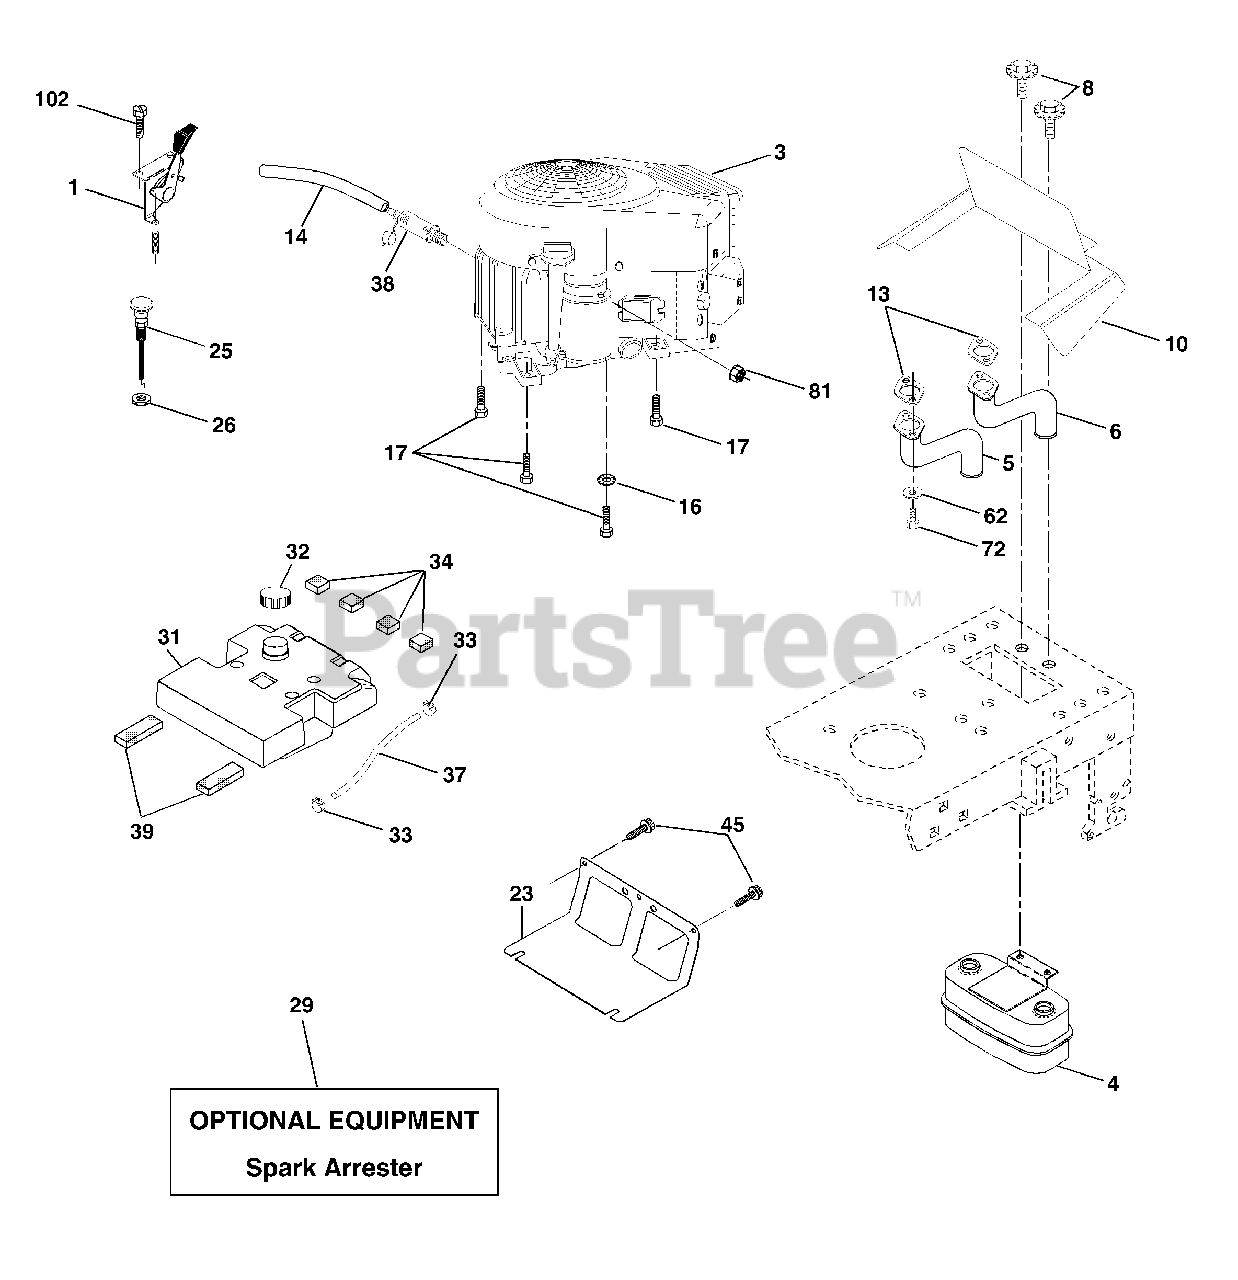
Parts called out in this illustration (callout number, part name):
1	Control Throttle
4	Muffler Asm Twin Lo-Tone
5	Pipe Exhaust LH Intek
6	Pipe Exhaust RH Intek
8	Bolt 5/16-18 UNC x 3/4 w/Sems
10	Shield Browning Intek II
13	Muffler Gasket
14	Tube Drain Oil Easy
16	Washer Lock Ext Tooth 3/8
17	Screw Thdrol 3/8-16 x 1-1/2
23	Shield Heat
25	Choke Control
26	Nut, Keps 3/8-24 UNF
29	Kit Spark Arrestor (Flat Scrn)
31	Tank Fuel 3 50 Rear
32	Cap Asm Fuel W/sym Vented
33	Clamp Hose Black
34	Pad, Spacer
37	Line Fuel
38	Plug Drain Oil Easy
39	Pad, Idler
45	Screw Hexwsh Thdr 3/8-16 x 3/4
62	Washer Lock 5/16
72	Screw Hex Hd Cap 5/16-18 x 3/4
81	Nut Keps Hex 1/4-20 UNC
102	Screw Hw Hd Hi-Lo #13-16 x 3/4
